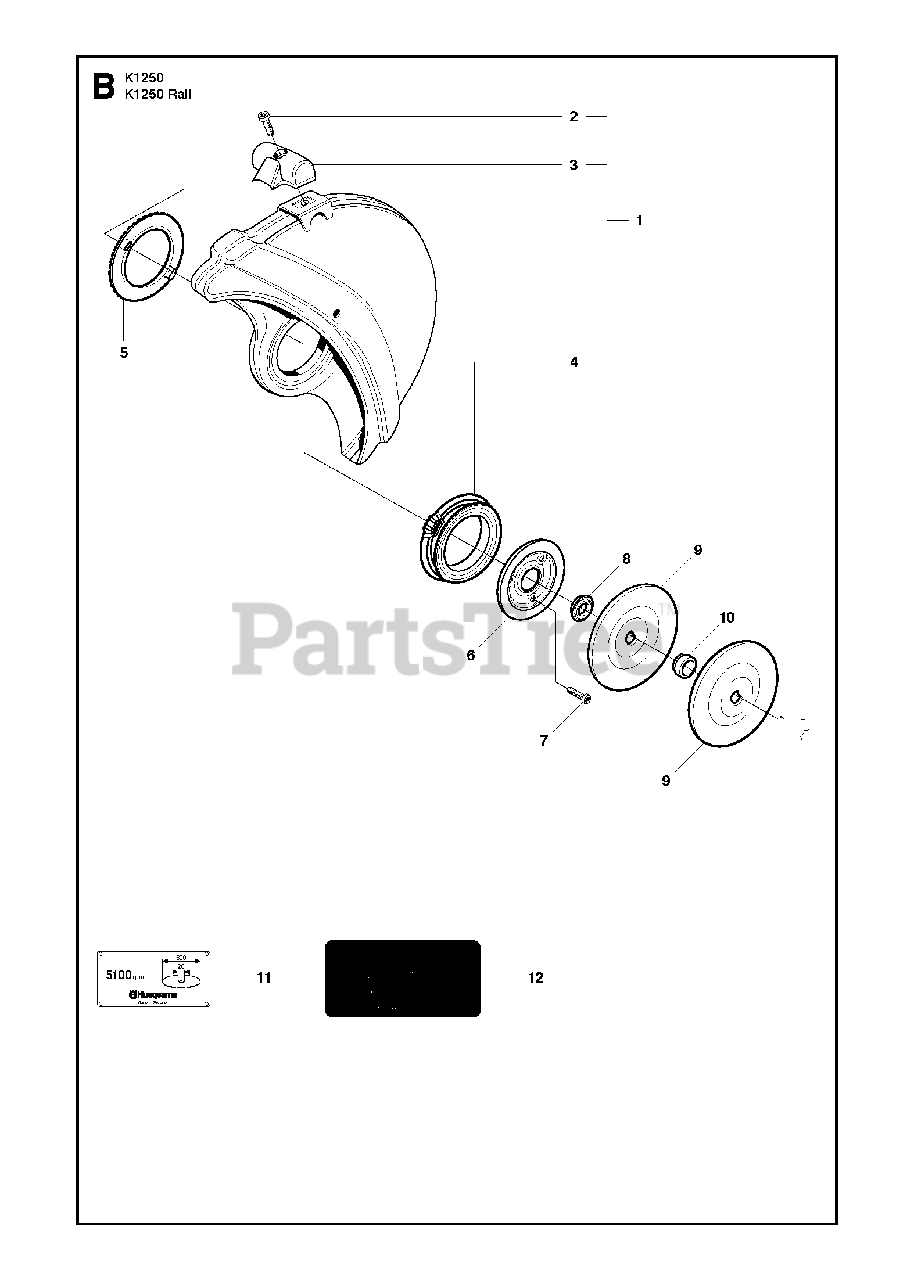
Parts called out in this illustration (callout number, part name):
1	WHEEL GUARD"14"""
1	GUARD"16"""
1	WHEEL GUARD ASSY"Rail 14"""
1	WHEEL GUARD"Rail 16"""
2	SCREW IHSCM
8	SUPPORT FLANGEK1250 A
8	SUPPORT FLANGEK1250 Rail
9	FLANGE WASHERDiam 105 mm
9	FLANGE WASHERDiam 119 mm
10	KITDiam 20 mm
10	KITDiam 22,2 mm
10	KITDiam 25 mm
10	BUSHINGDiam 30,5 mm
11	LABEL"14"". Diam 20mm"
11	LABEL"14"". Diam 22,2 mm"
11	LABEL"14"". Diam 25,4mm"
11	LABEL"16"". Diam 20mm"
11	LABEL"16"". Diam 22,2mm"
11	LABEL"16"". Diam 25,4mm"
12	DECAL"Japan, 14"""
12	DECAL"Japan, 16"""
